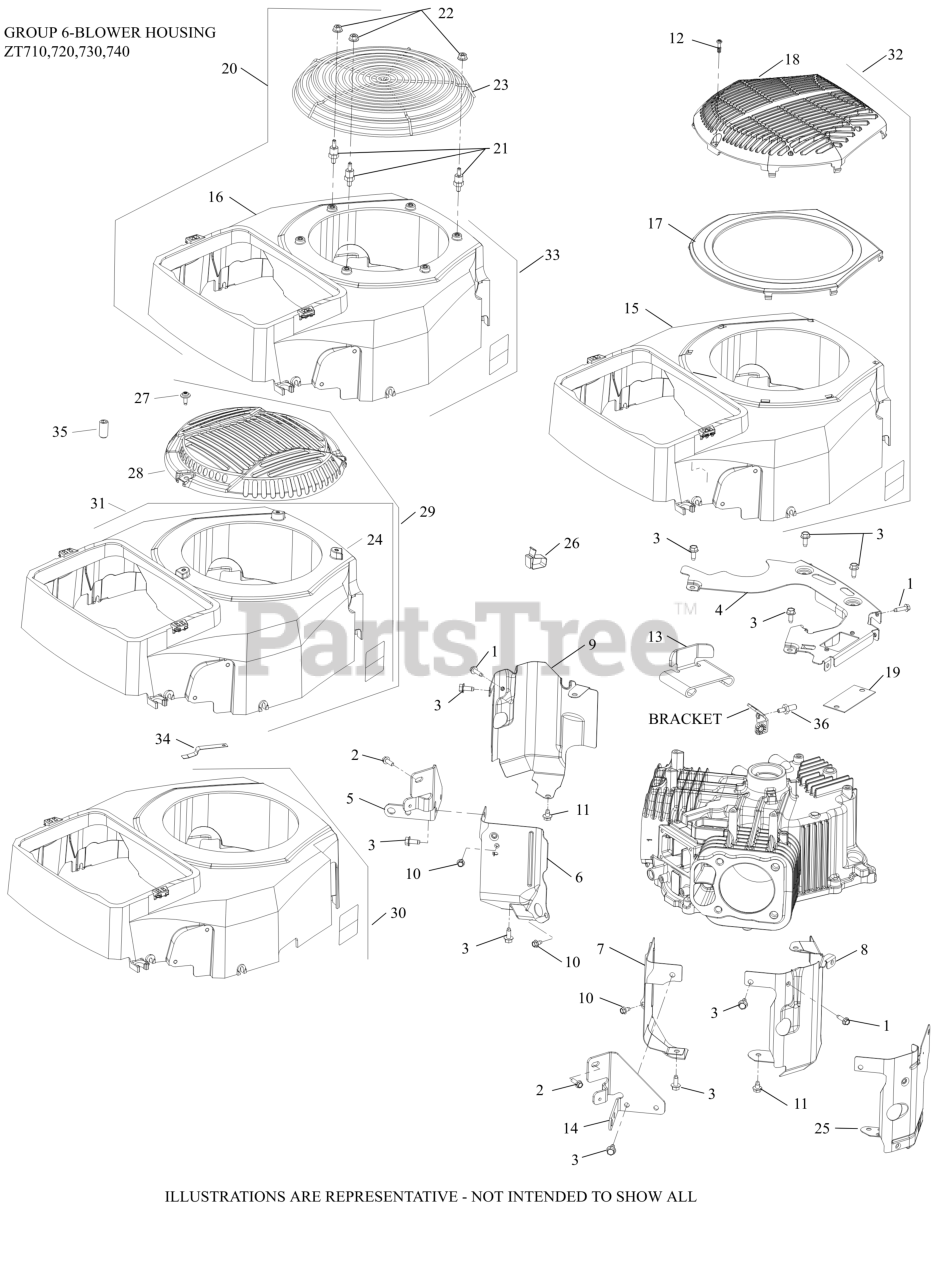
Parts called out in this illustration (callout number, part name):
1	SCREW, THD FRM-USE 25 086 473-S
2	SCREW, HI-LOW
3	SCREW, THREAD FORMING
4	PLATE, BACKING
5	BRACKET, AIR CLEANER BASE (#1 SIDE)
6	BAFFLE, VALLEY #1
7	BAFFLE, VALLEY #2
8	BAFFLE, LEFT BARREL
9	BAFFLE, RIGHT BARREL
10	SCREW, THREAD FORMING
14	BRACKET, AIR CLEANER BASE (#2 SIDE)
16	KIT, BLOWER HOUSING
24	KIT, BLOWER HOUSING
27	SCREW, SEMS
28	GUARD, GRASS SCREEN (METAL)
